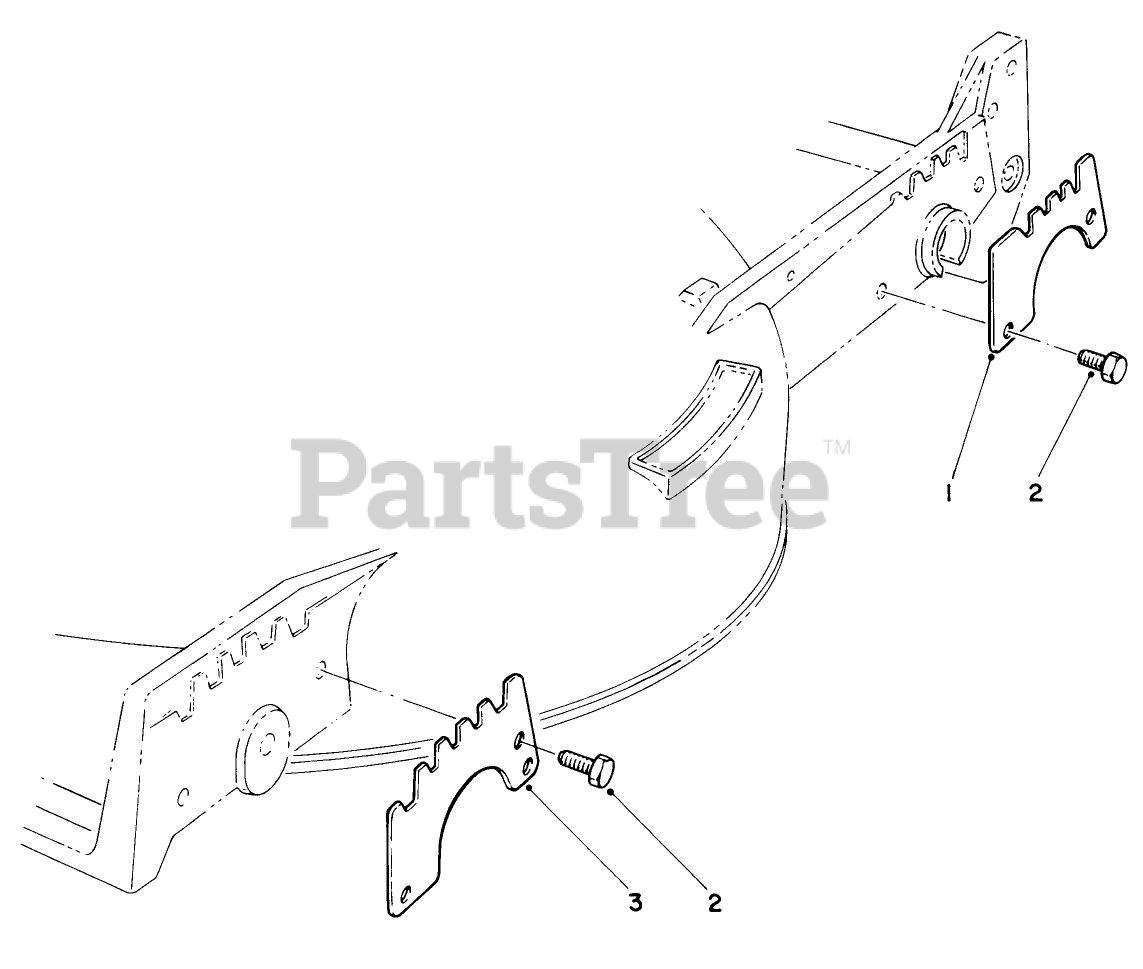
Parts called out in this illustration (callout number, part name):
1	WEAR PLATE,REAR
2	SCREW-HWH
3	WEAR PLATE
